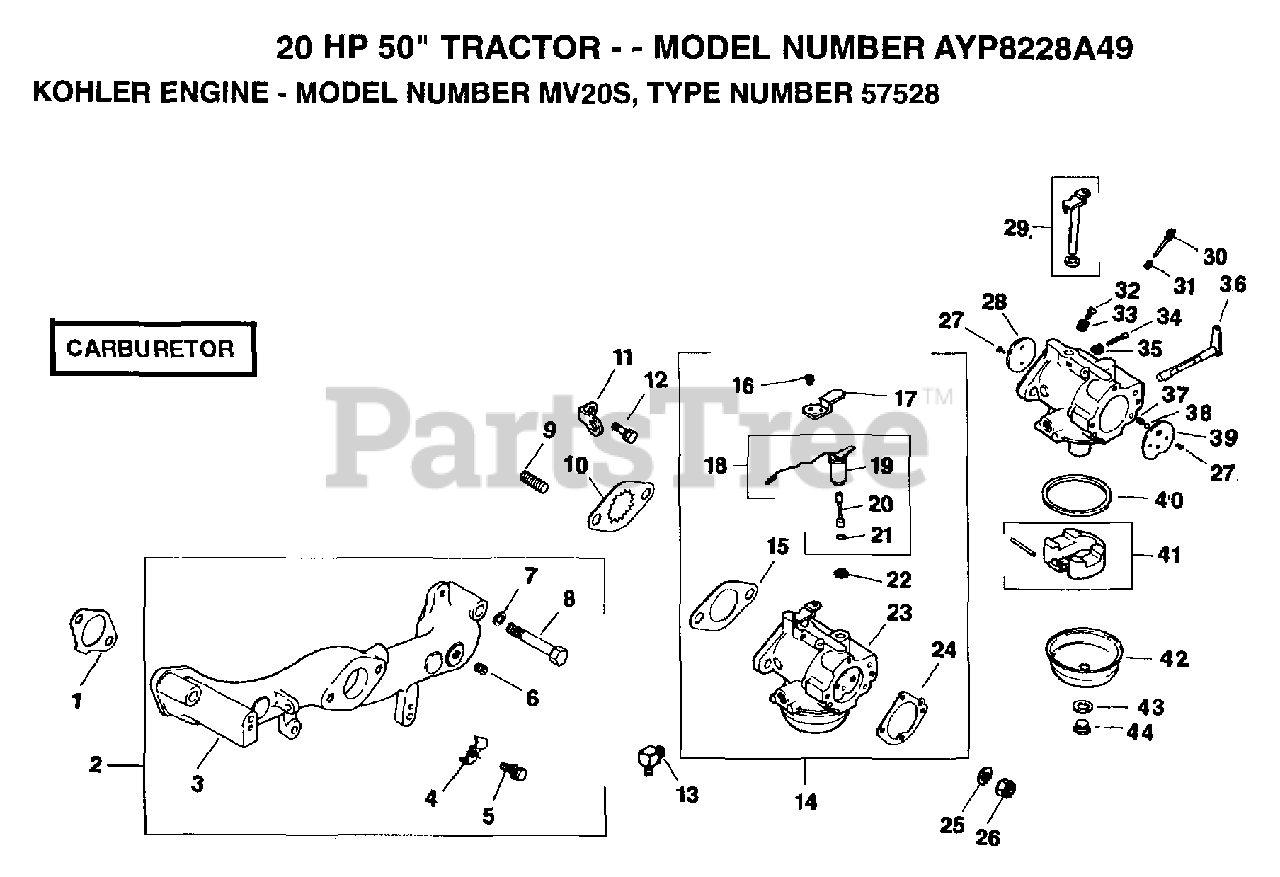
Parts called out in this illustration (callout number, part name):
4	CLAMP
5	SCREW
6	PLUG
7	WASHER
8	SCREW, HEX CAP 5/16-18 X 1-14 (4)
11	STRAP
12	SCREW
14	KIT, CARB. W/GASKET
15	GASKET
16	SCREW, 1/4-20 X 1
17	BRAKET, SOLENOID
18	KIT, SOLENOID
20	ROD, SOLENOID
22	GASKET, NEEDLE SEAT
24	GASKET, AIR CLEANER
25	WASHER, INTERNAL TOOTH
26	NUT
29	SHAFT, THTLE,W/LEVER & SEAL
44	SCREW, BOWL RETAINER
